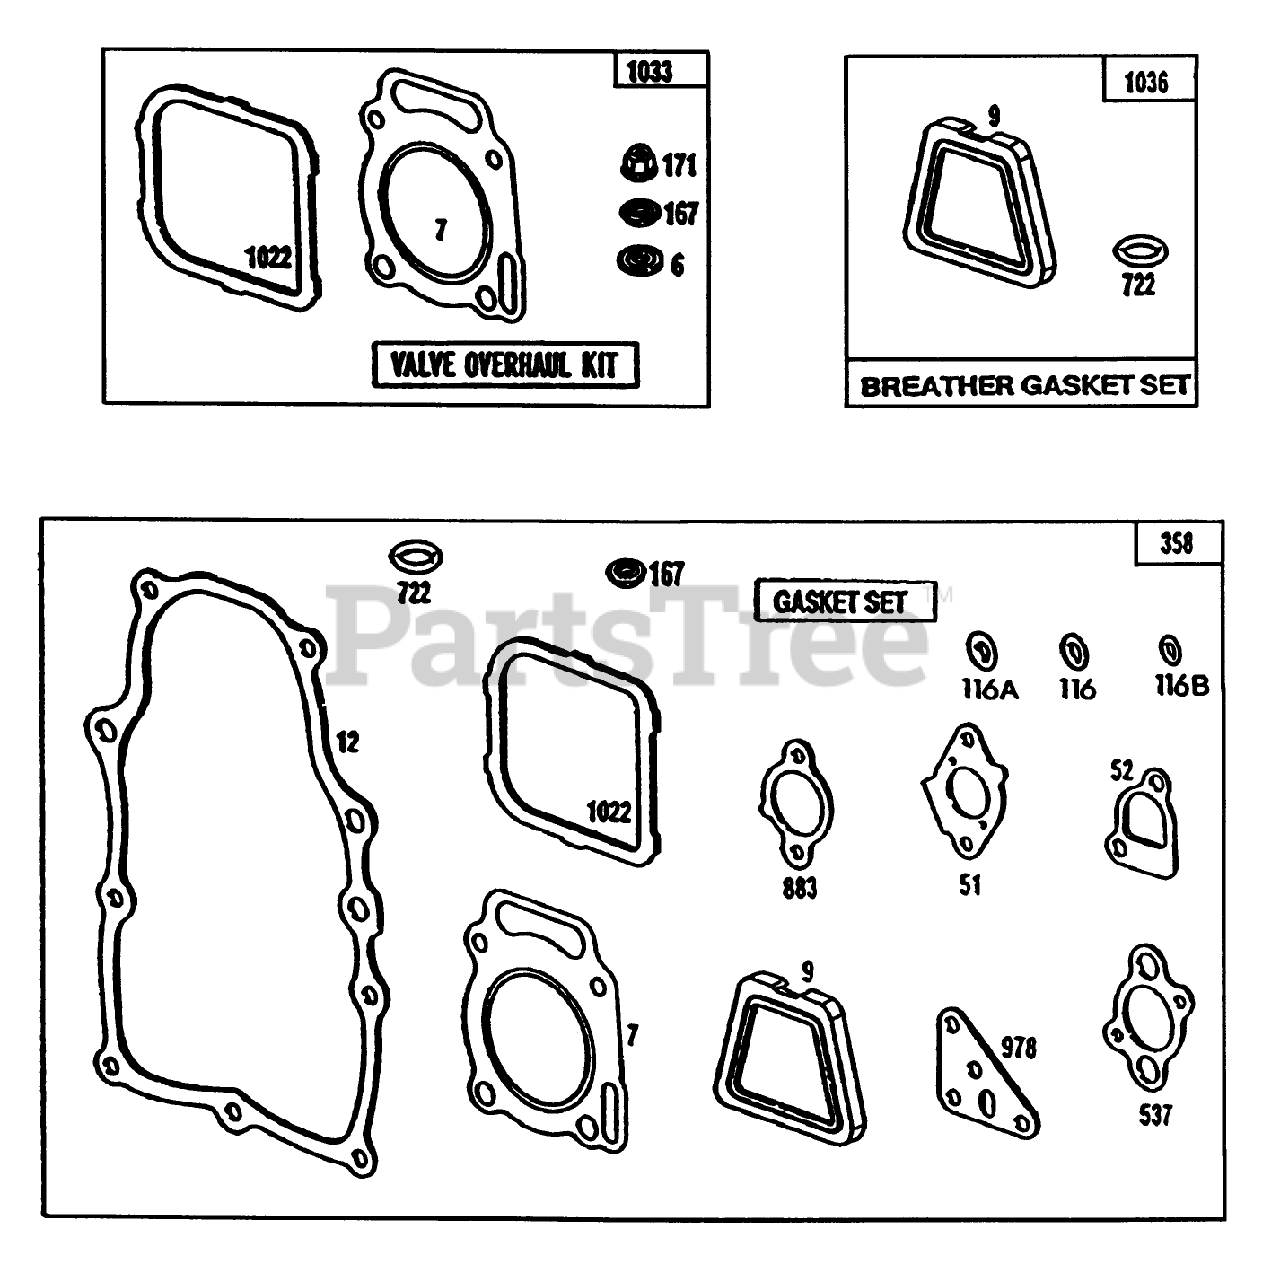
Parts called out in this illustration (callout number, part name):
6	BRIGGS-805193
7	BRIGGS-807986
9	BRIGGS-805395
12	BRIGGS-805312
51	BRIGGS-805149
52	BRIGGS 805023
116	BRIGGS-805058
116A	BRIGGS-805198
116B	Kit-Gasket Sealing
167	BRIGGS-805420
171	BRIGGS 805019
358	BRIGGS-807989
537	BRIGGS 805655
883	GSKT-EXHST MANIFOLD
978	BRIGGS 805250
1022	BRIGGS-805028
